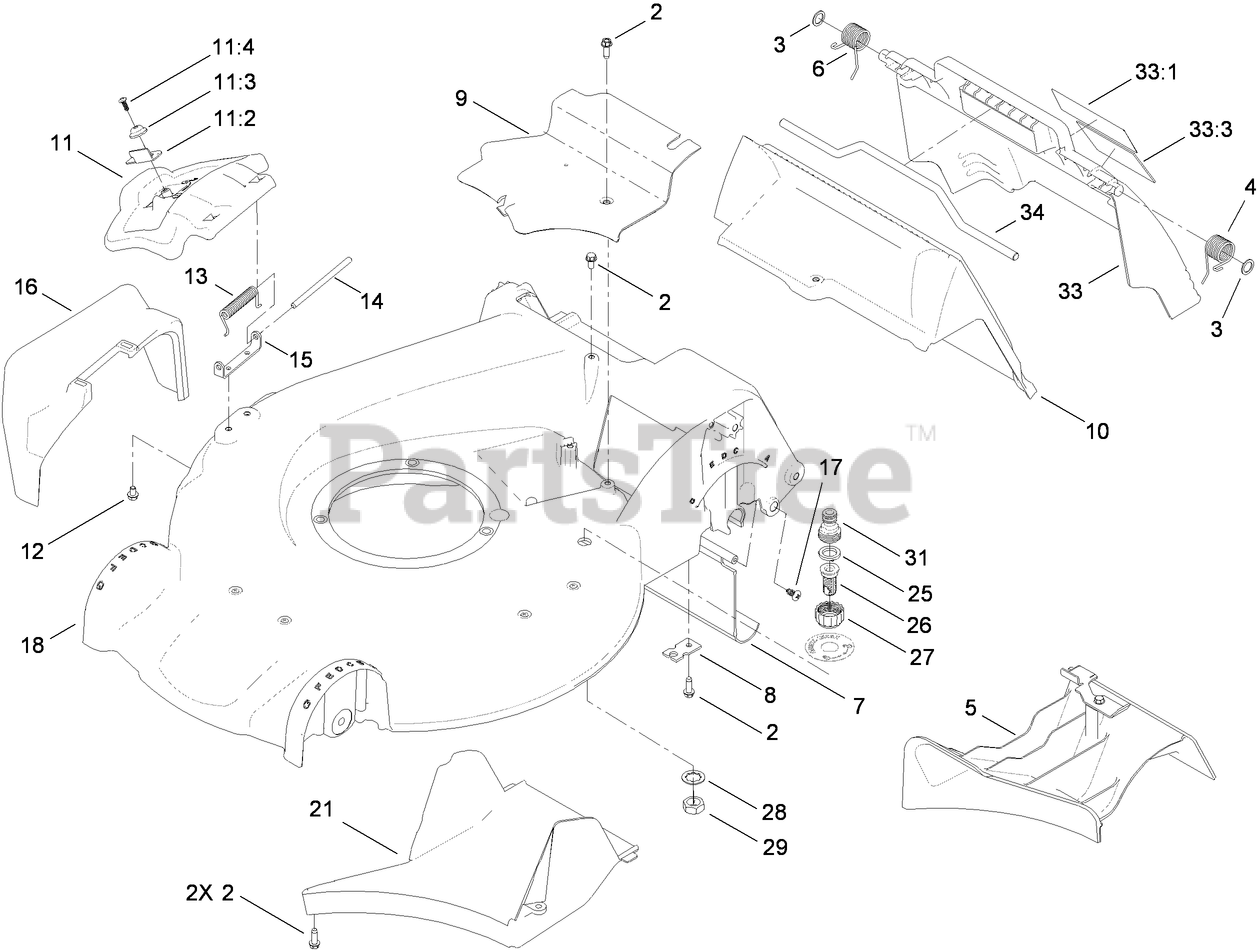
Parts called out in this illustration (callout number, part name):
2	SCREW-HWHTF
3	WASHER-NYLON
4	SPRING-TORSION
5	MULCH PLUG ASM
6	SPRING-TORSION
9	COVER-BELT
11	DISCHARGE DOOR ASM
11:2	LATCH-DOOR
11:3	CAP-DOOR
11:4	SCREW-PLASTITE
12	SCREW-HWH
13	SPRING-TORSION
15	BRACKET-COVER
16	CHUTE-DISCHARGE, SIDE
17	SCREW-PTH
18	HOUSING ASM
21	TUNNEL-DISCHARGE
25	WASHER-SEAL, WASHOUT PORT
26	PORT-WASHOUT
27	COUPLING-HOSE, WASHOUT PORT
28	WASHER-LOCK
29	NUT-JAM
31	ADAPTER-CONNECT, QUICK
33	REAR DOOR ASM
33:1	DECAL-WARNING
33:3	DECAL-WARNING
34	ROD-DEFLECTOR
